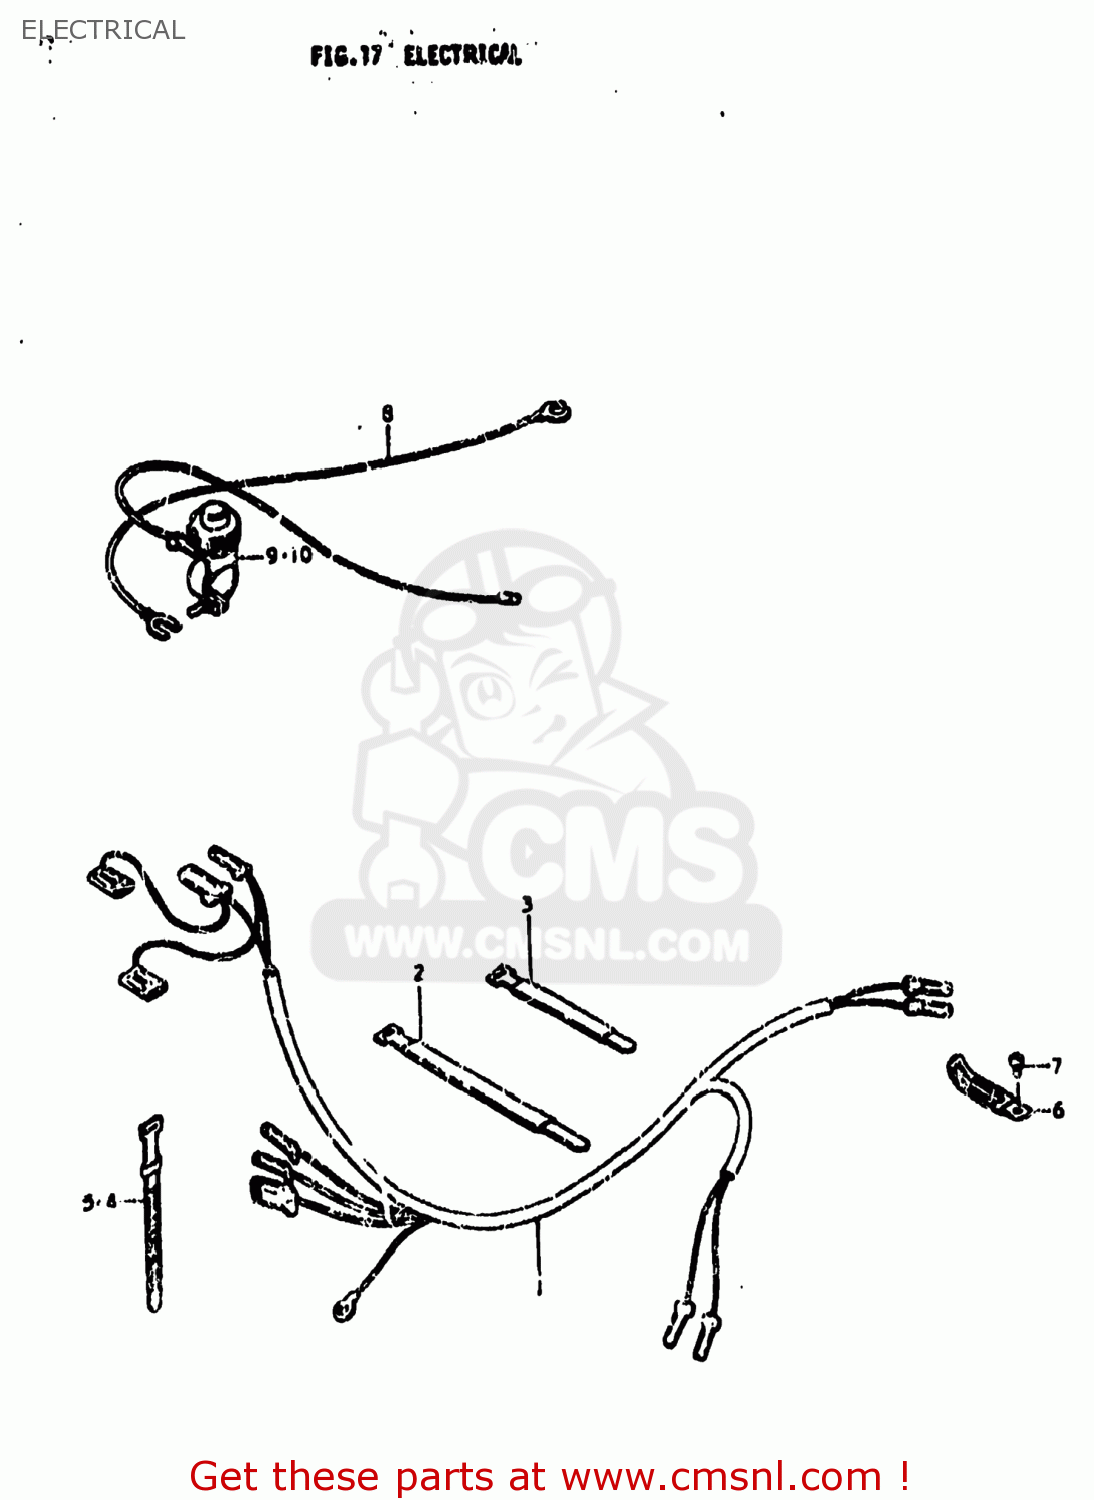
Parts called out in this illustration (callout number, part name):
1	HARNESS,WIRING
2	CLAMP
3	CLAMP
4	CLAMP(L:120)
5	CLAMP
6	CLAMP
7	CROSS SCREW (4X8)
8	WIRE,ENGINE STOP EARTH
9	SWITCH ASSEMBLY
10	SWITCH ASSEMBLY
